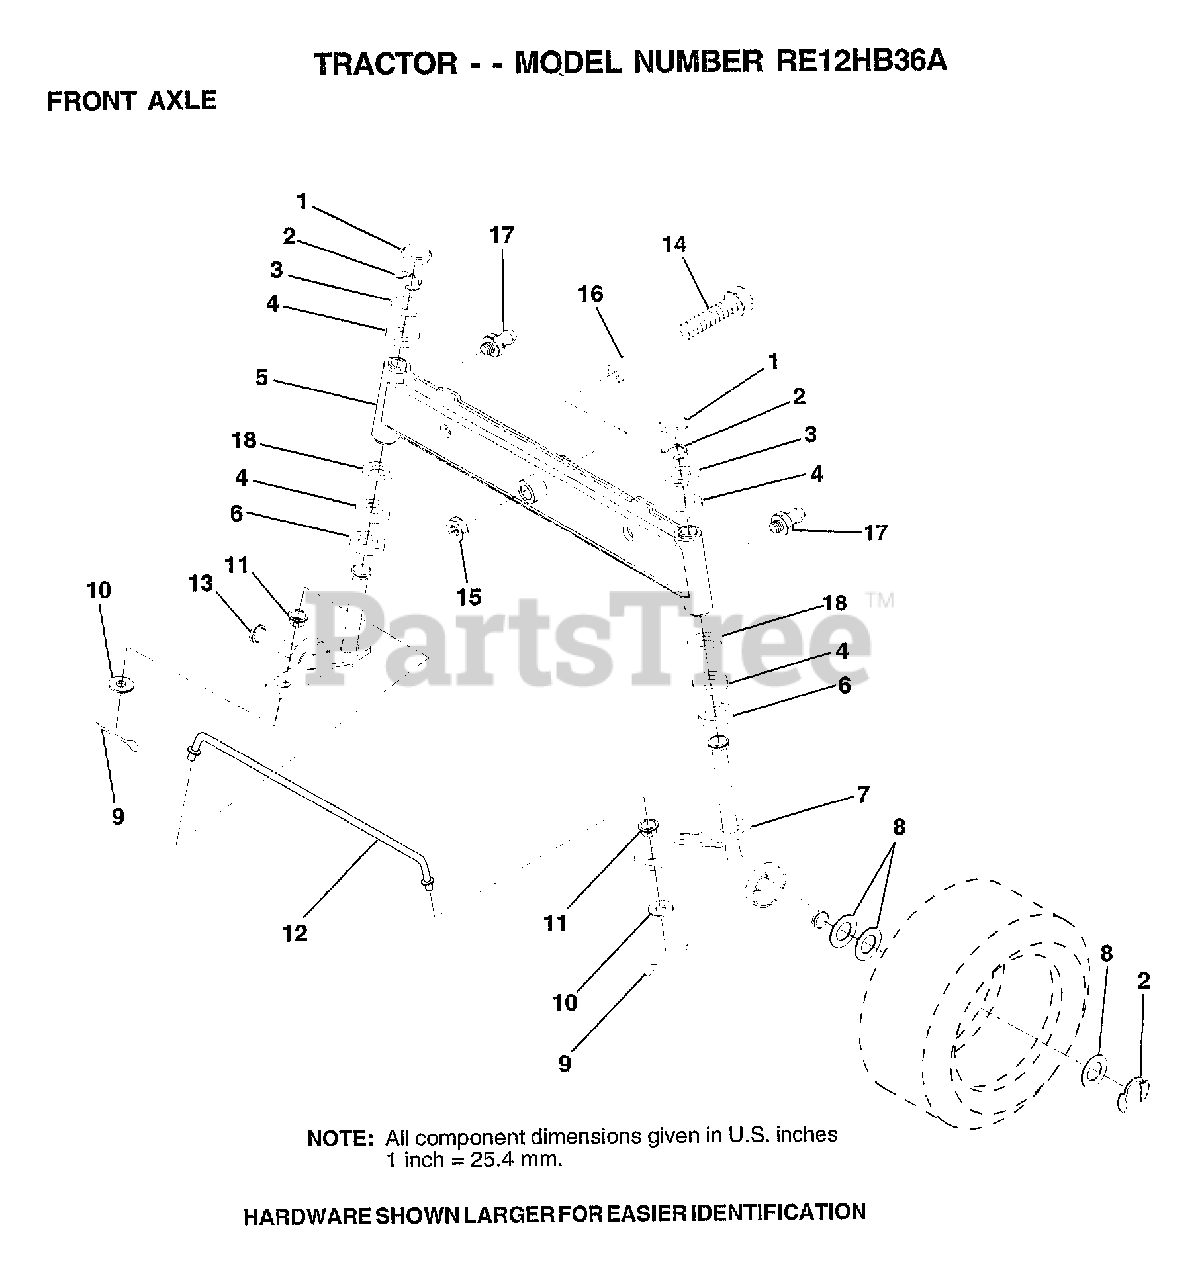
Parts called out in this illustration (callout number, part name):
1	CAP
2	RING
3	WASHER
4	COL. SRTG. BEAR.
5	AXLE ASM FRONT
6	WASHER .T
7	SPINDLE.ASSY.RH
8	WASHER
9	COTTER PIN
10	WASHER
11	BUSHING.DRAGLINK
12	TIE ROD
13	SPINDLE.ASSY.LH
14	BOLT HEX 5/8-11
15	"NUT-LOC,FLANGE LT"
16	BEARING
17	ZERK M
18	WASHER
